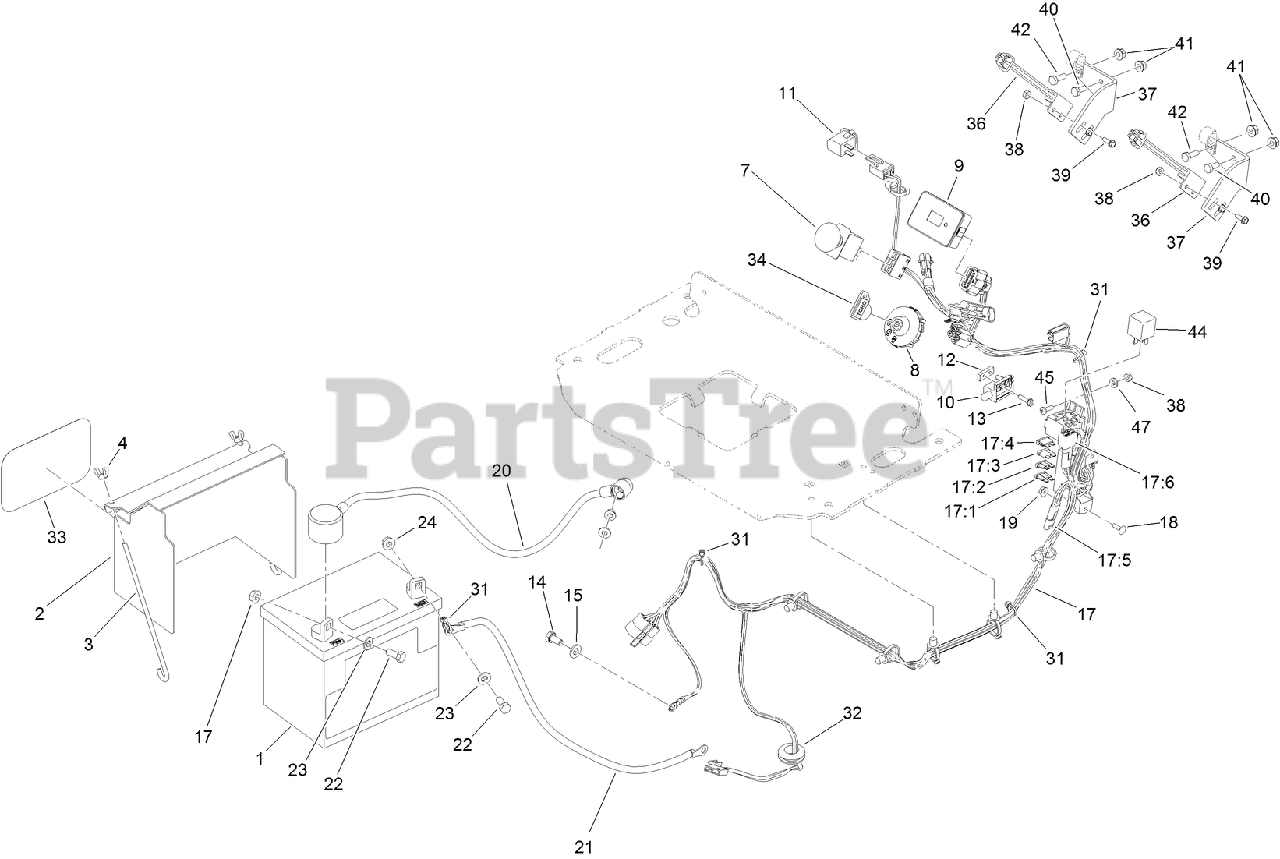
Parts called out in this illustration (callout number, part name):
1	BATTERY-DRY
2	COVER-BATTERY
3	BOLT-HOLDDOWN
4	WINGNUT
7	SWITCH-PTO, ON-ON-(ON)
8	SWITCH-IGNITION
9	MODULE-HOUR METER
10	SWITCH-CLOSED, NORMALLY
11	SWITCH-BAIL
12	PLATE-TAPPED
13	SCREW-HWH
14	SCREW-HH
15	WASHER-PLAIN
17	HARNESS-WIRE
17:1	FUSE-BLADE, 30 AMP
17:2	FUSE-BLADE, 25 AMP
17:3	FUSE-BLADE, 10 AMP
17:4	FUSE-BLADE, 15 AMP
17:5	CAP-PLUG
18	BOLT-CARR
19	NUT-HF
20	CABLE-BATTERY, POSITIVE
21	CABLE-BATTERY, BLACK
22	SCREW-HH
23	WASHER-PLAIN
24	NUT-HHF, SMOOTH
31	TIE-CABLE
32	GROMMET
33	DECAL
34	KEY-IGNITION
36	SWITCH-PROXIMITY
37	BRACKET-MOUNT, SWITCH
38	NUT-LOCK, NI
40	SCREW-HH
41	NUT-HHF
42	SCREW-HH
45	SCREW-PPH
47	WASHER-FLAT
